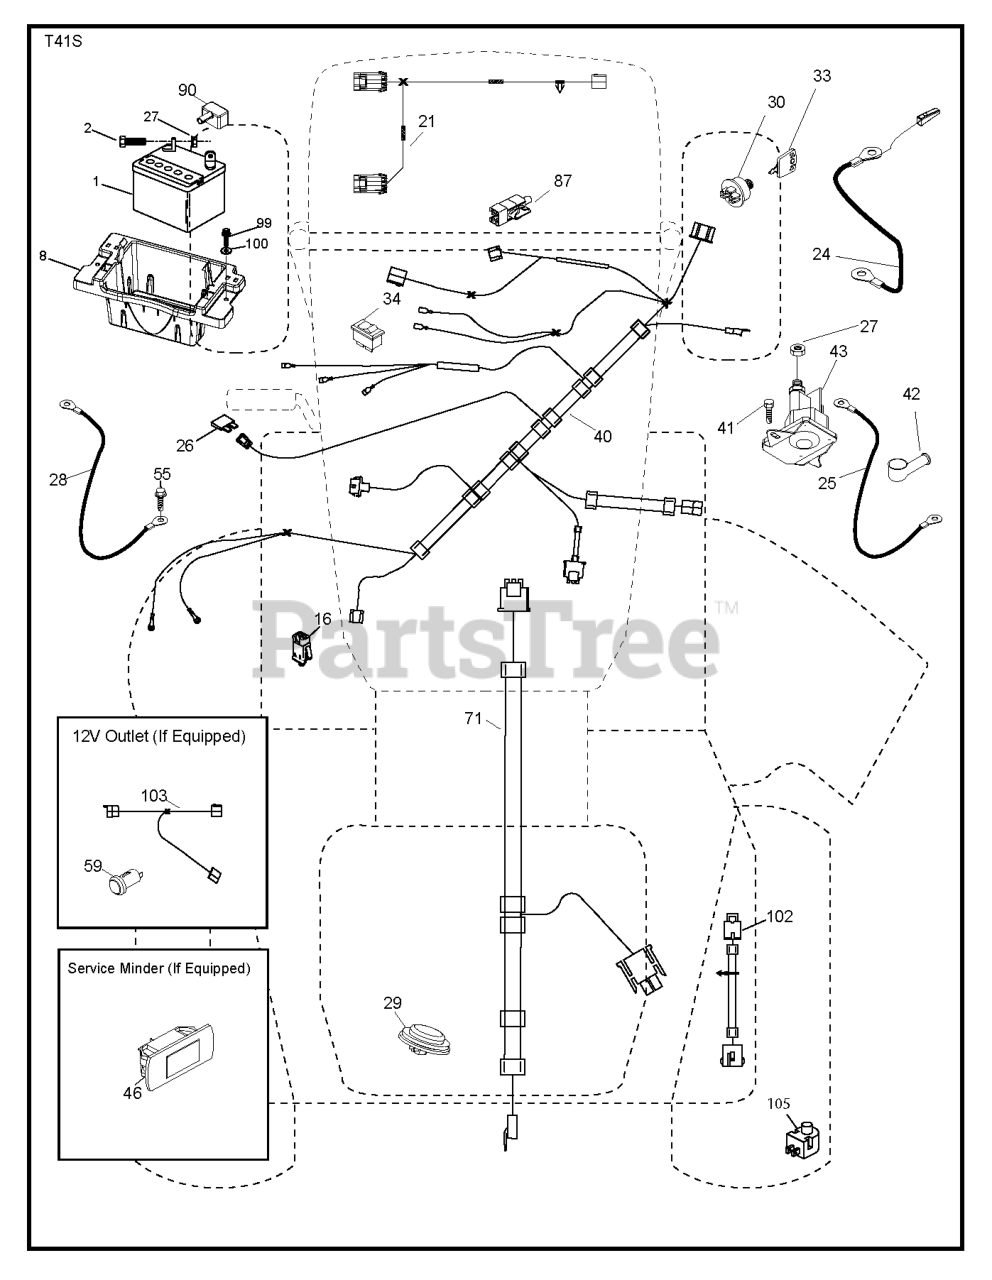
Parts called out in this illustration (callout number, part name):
1	Battery 12 Volt 25 Amp
2	BOLT.HEX.1/4.X.3/4.DICHROMATE
8	TRAY.ASM.BATTERY.FRT.TEX.CARB
16	SWITCH INTERLOOK PUSH-IN
21	HARNESS LIGHT ASSY TRACTOR,
24	CABLE.FRBATT.W/WIRE.8GA.8
25	CABLE.STARTER.8GA.17.5
26	FUSE 20AMP
27	NUT
28	CABLE.GROUND.21"BLK.8GA.90T
29	SWITCH.SEAT.DELTA.OPC.
30	SWITCH.IGN.DELTA.W.LGH.ROS
33	KEY.CHAIN.BLISTER.PACK.GEN.USA
40	HARNESS.IGN.DASH.CBL.YTGT.PRED
41	SCREW
42	TERMINAL COVER
43	SOLENOID.STARTER.BRASS.PLUNGER
46	GUAGE.SRVCMNDR.HRMTR.
55	SCREW 5/16"
71	HARNESS-CHASSIS SUB
87	SWITCH.INTRLCK.CLUTCH.
90	COVER.TERMINAL.BATTERY
99	SCREW HEXWSHR 1/4-20X3/4
102	HARNESS PIGTAIL PCH TEX ROS
105	REVERSE SWITCH
